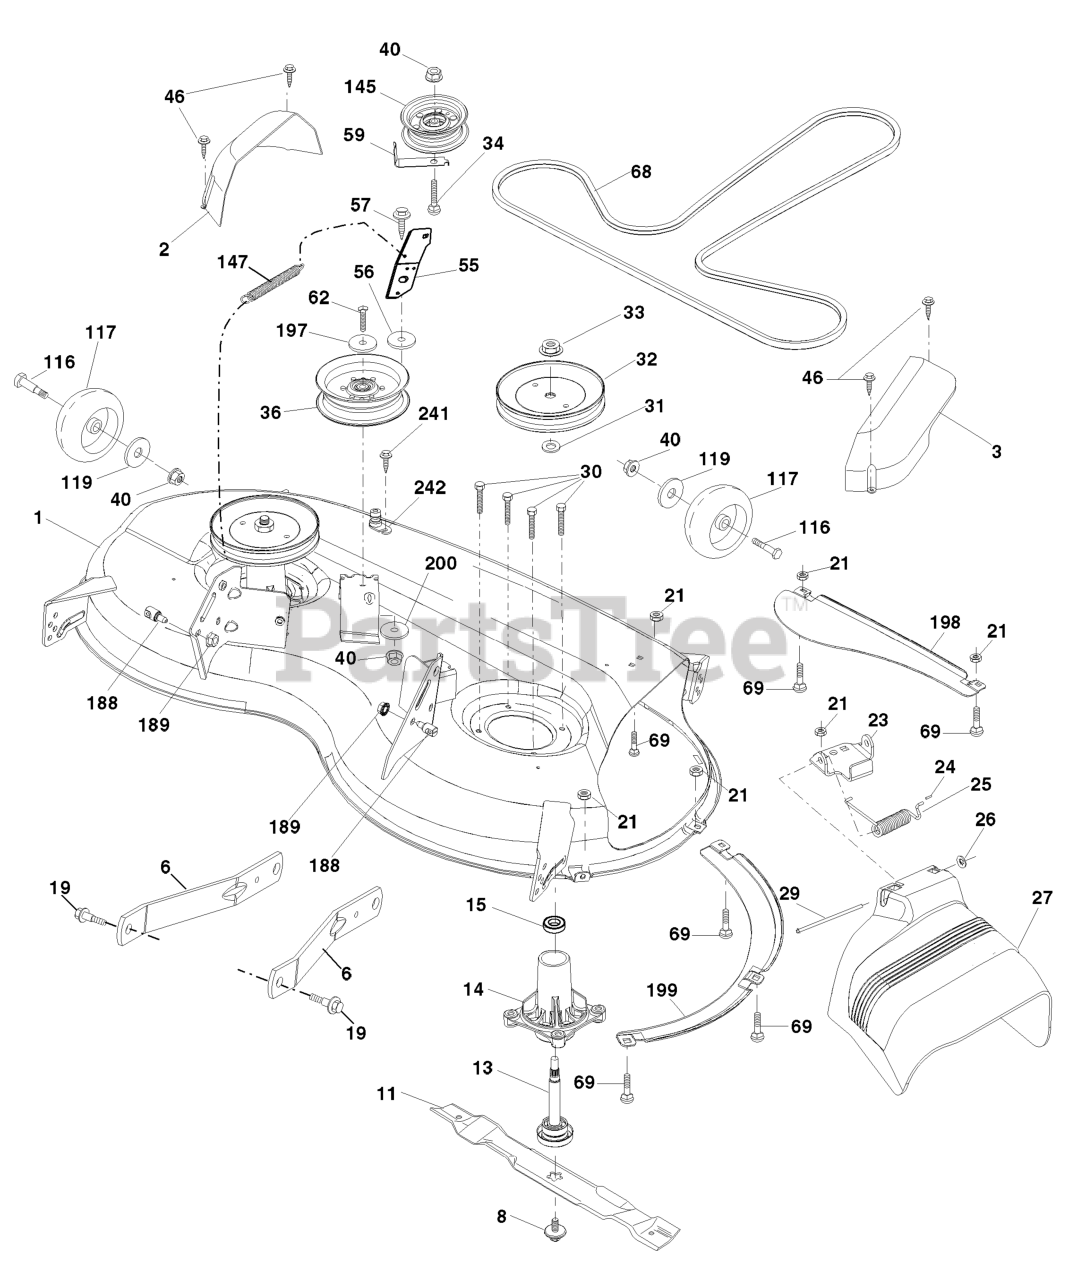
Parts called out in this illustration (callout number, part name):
1	DECK.WELDMENT.46"
2	COVER.MANDREL.RH.46"
3	COVER.MANDREL.LH.46"
6	ARM.SUSPENSION.MOWER.R
8	BOLT.WASHER.ASM.7/16-2
11	BLADE.MOWER.46".HI.LIFT
13	SHAFT.ASM.MDRL.N/GREASE.38
14	RP.HOUSING.MANDREL.4PT.
19	BOLT.SHOULDER
21	LOCKNUT
23	BRKT.DEFLECTOR.38"2005+
24	CAP-SLEEVE LT
25	SPRING.TORSION.DEFLECT
26	NUT PUSH M
27	SHIELD.DEFLECTOR.MOWER.46"BLAC
29	ROD.HINGE
30	SCREW, WASHER HEAD
31	WASHER.SPACER.MANDREL
32	PULLEY.MANDREL.5.438.PD
33	NUT.FLANGE.LOCK.TOP
34	BOLT.3/8-16X1.50
36	PULLEY.IDLER.2006
40	NUT LOCK FLG 3/8-16 UNC
46	SCREW.1/4-20X5/8
55	IDLER.ARM
56	SPACER.RETAINER
57	SCREW 3/8-16X1
59	GUARD, BELT
62	BOLT-HEX EAK
68	V-BELT
69	BOLT
116	BOLT.SHOULDER.3/8-16X3-5/8.
117	RP WHEEL. GUAGE RALLY
119	WASHER
145	PULLEY.IDLER.48"PRIMARY
147	SPRING.MOWER.DRIVE.ELECTRIC
188	STUD.FASTNER.W/ANTI-ROTATE
189	NUT LOCK HEX FLANGE 5/16-18
197	WASHER
198	BAFFLE CENTER FRONT
199	BAFFLE FRONT RH
200	Washer 13/32 x 2 x 10 Ga.
241	SCREW.TT.#10-32X.5.3/8.FLANGE
242	PORT.WASHOUT
